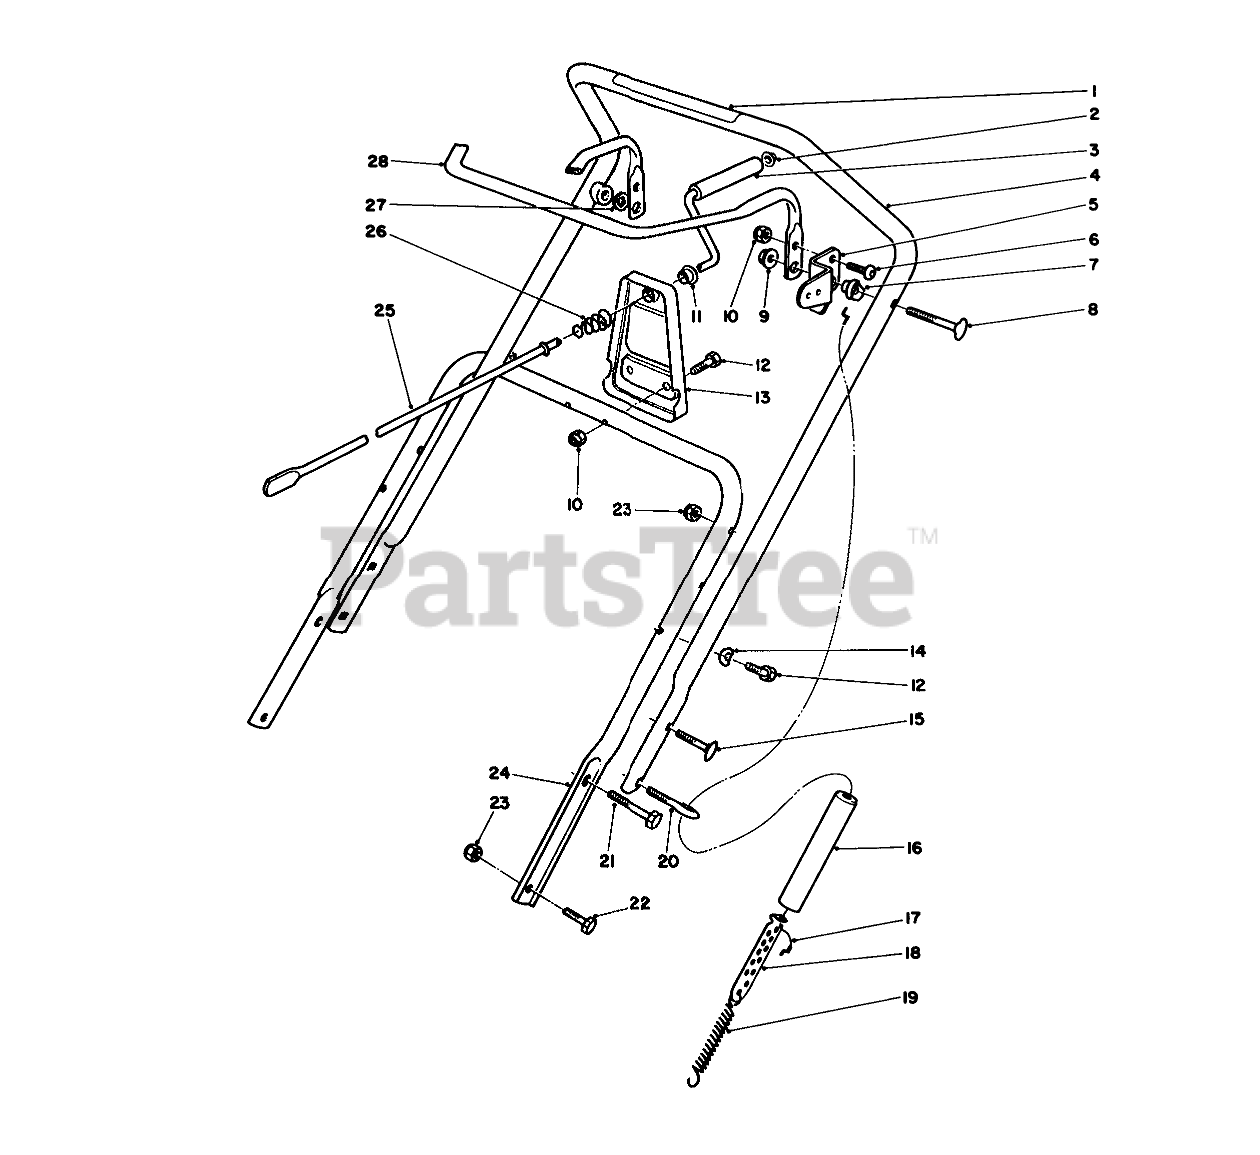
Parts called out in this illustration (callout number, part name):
1	Decal-Rotor Drive
2	RETAINER-PUSH ON
3	GRIP-CONTROL, CHUTE
4	Upper Handle Assembly (Incl. Ref. #1) (Model 38180)
5	Arm-Clutch Cable
6	SCREW-HSBH
7	SPACER-BAR, CONTROL
8	SCREW-HANDLE
9	NUT-LOCK, NI
10	NUT-LOCK, NI
11	Bushing
12	SCREW-HH
13	Support-Crank
14	WASHER
15	SCREW
16	COVER-SPRING
17	CLUTCH CABLE
18	ADJUSTER-CABLE
19	SPRING-EXTENSION
20	BOLT-EYE
21	SCREW-HH
22	SCREW-HH
23	NUT-LOCK, NI
24	LOWER HANDLE
25	ROD-CRANK, CHUTE
26	SPRING-COMPRESSION
27	WASHER
28	Bar-Control
